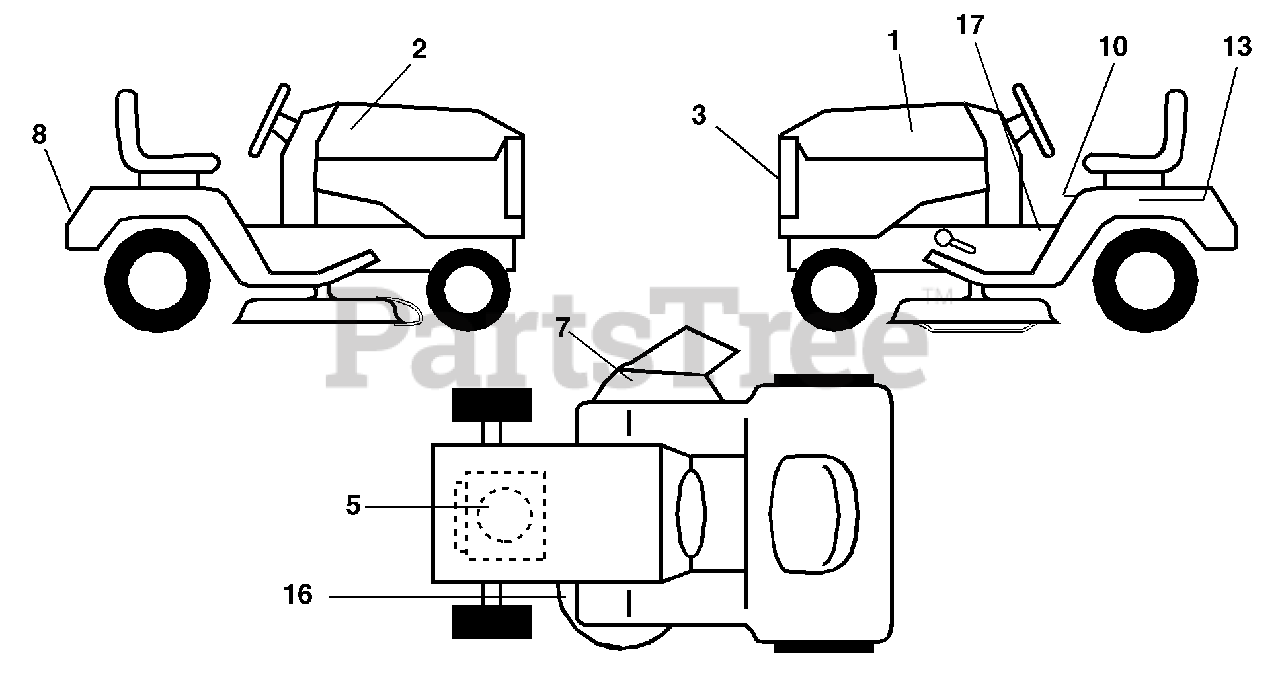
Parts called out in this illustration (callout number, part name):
1	Decal, Hood, L. H.
2	Decal, Hood, R. H.
3	Decal, Grille
5	Decal, Engine
7	Decal, Warning Multi/Lang
8	Decal, Logo, Fender
10	Decal Caution Fender
13	Decal, Caution, Battery
16	Decal, V-Belt Sch.
17	Decal, Inst. Oper.
